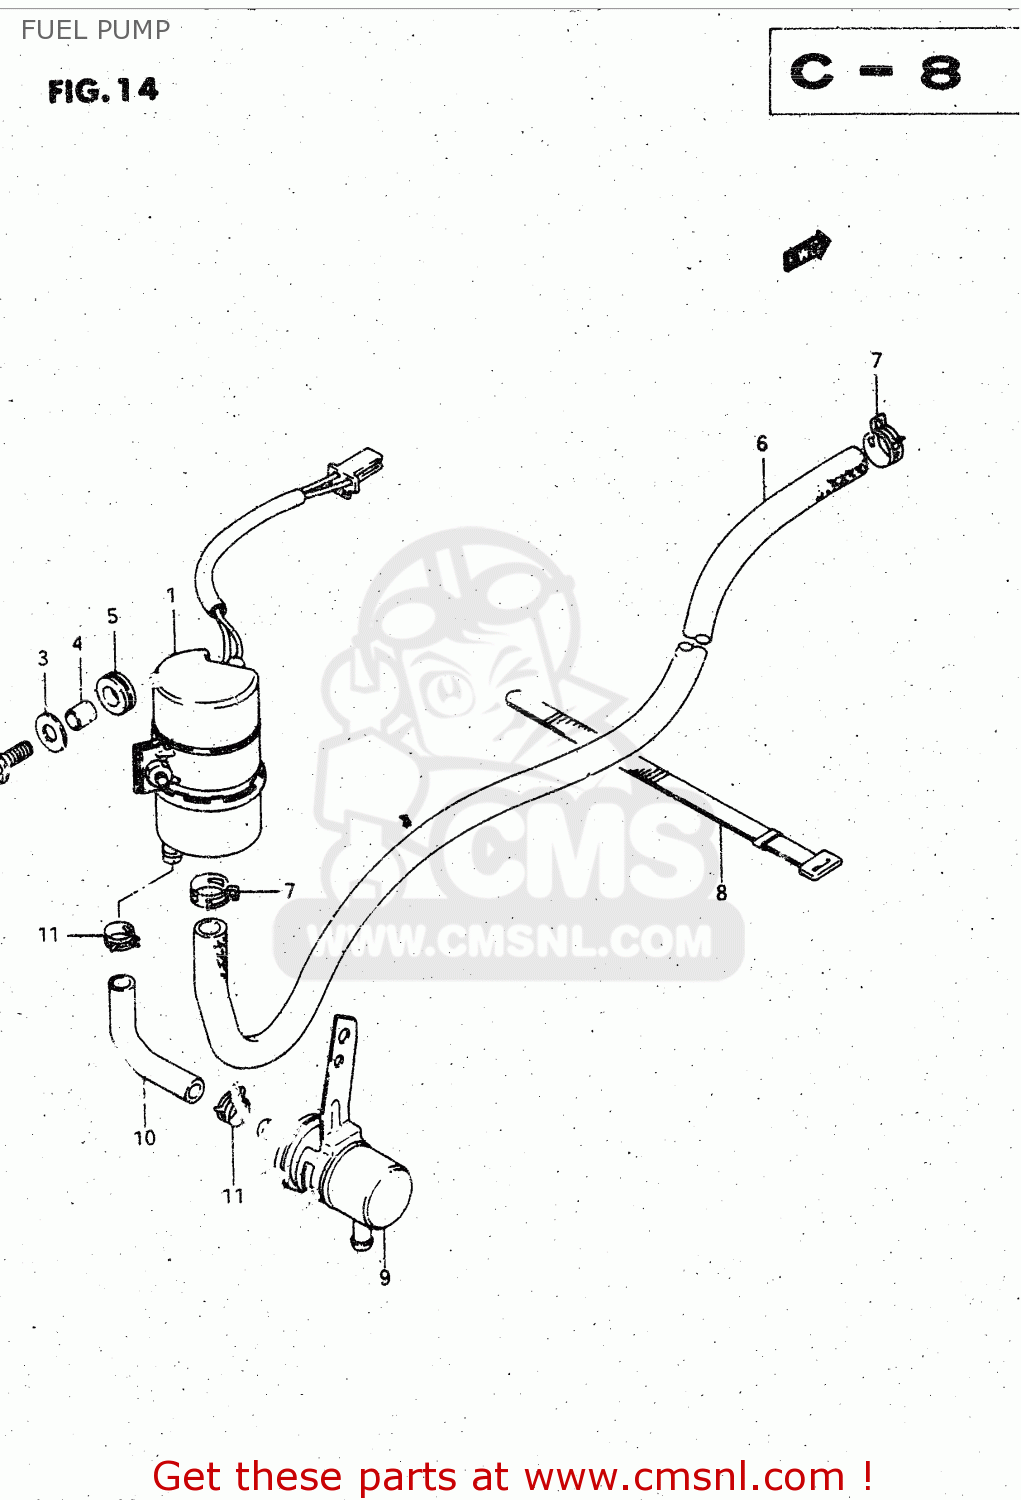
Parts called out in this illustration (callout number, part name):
1	PUMP ASSEMBLY,FUEL
2	BOLT
3	WASHER
4	SPACER
5	CUSHION
6	HOSE,FUEL
7	CLIP
8	CLAMP(L:187)
9	FILTER ASSY,FUEL
10	HOSE, FUEL (FILTER & PUMP)
11	CLIP
